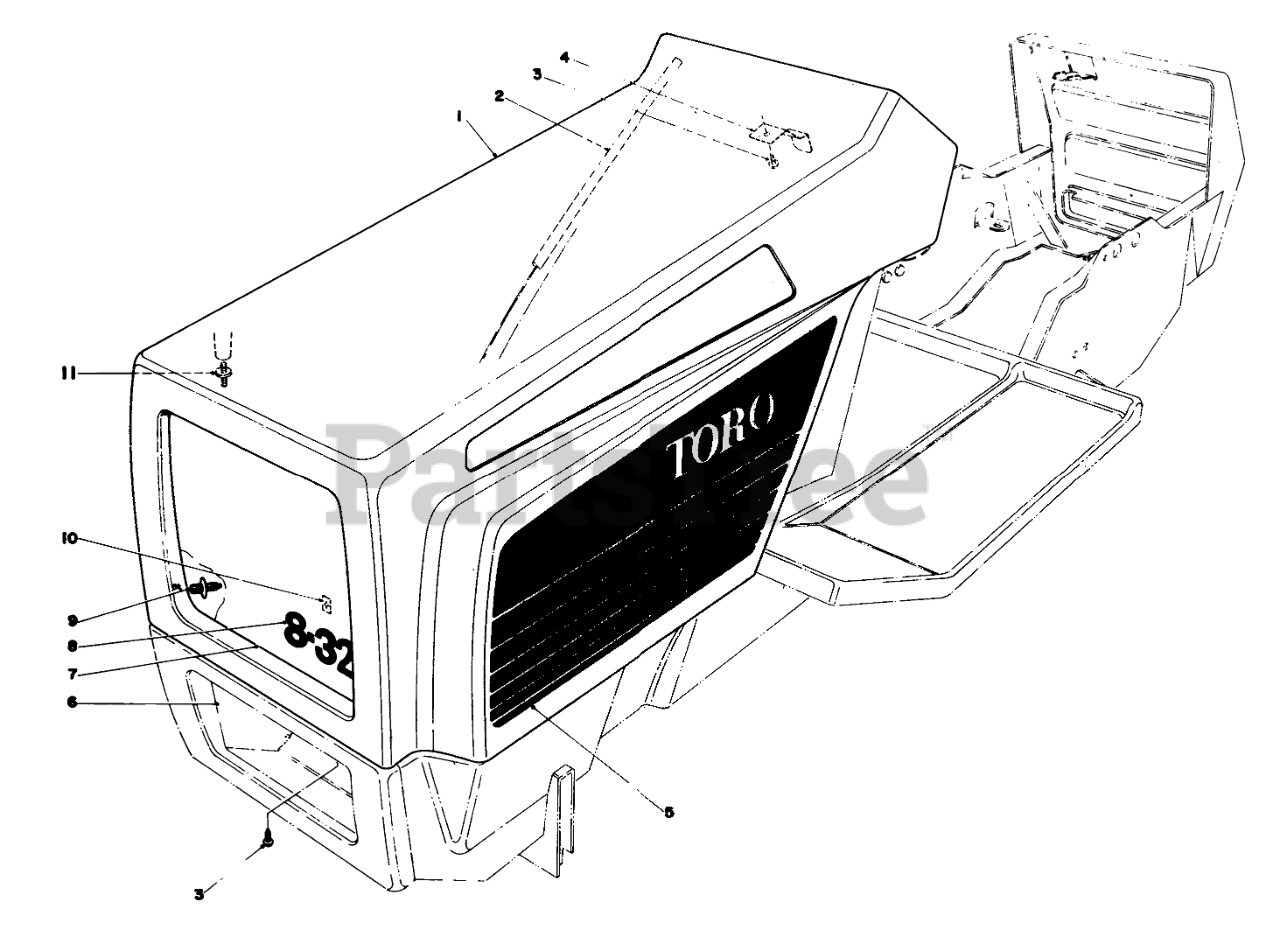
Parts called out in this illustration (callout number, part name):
1	Hood (Incl. Ref. #9 & 11)
2	RUBBER EXT SEAL
3	SCREW-HWHTF
4	SPRING LATCH
5	Decal Hood LH.
6	LOWER GRILLE
7	Grille-Hood
8	Nameplate Grille
9	HINGE BRKT STUD
11	Stud Hood Duct
